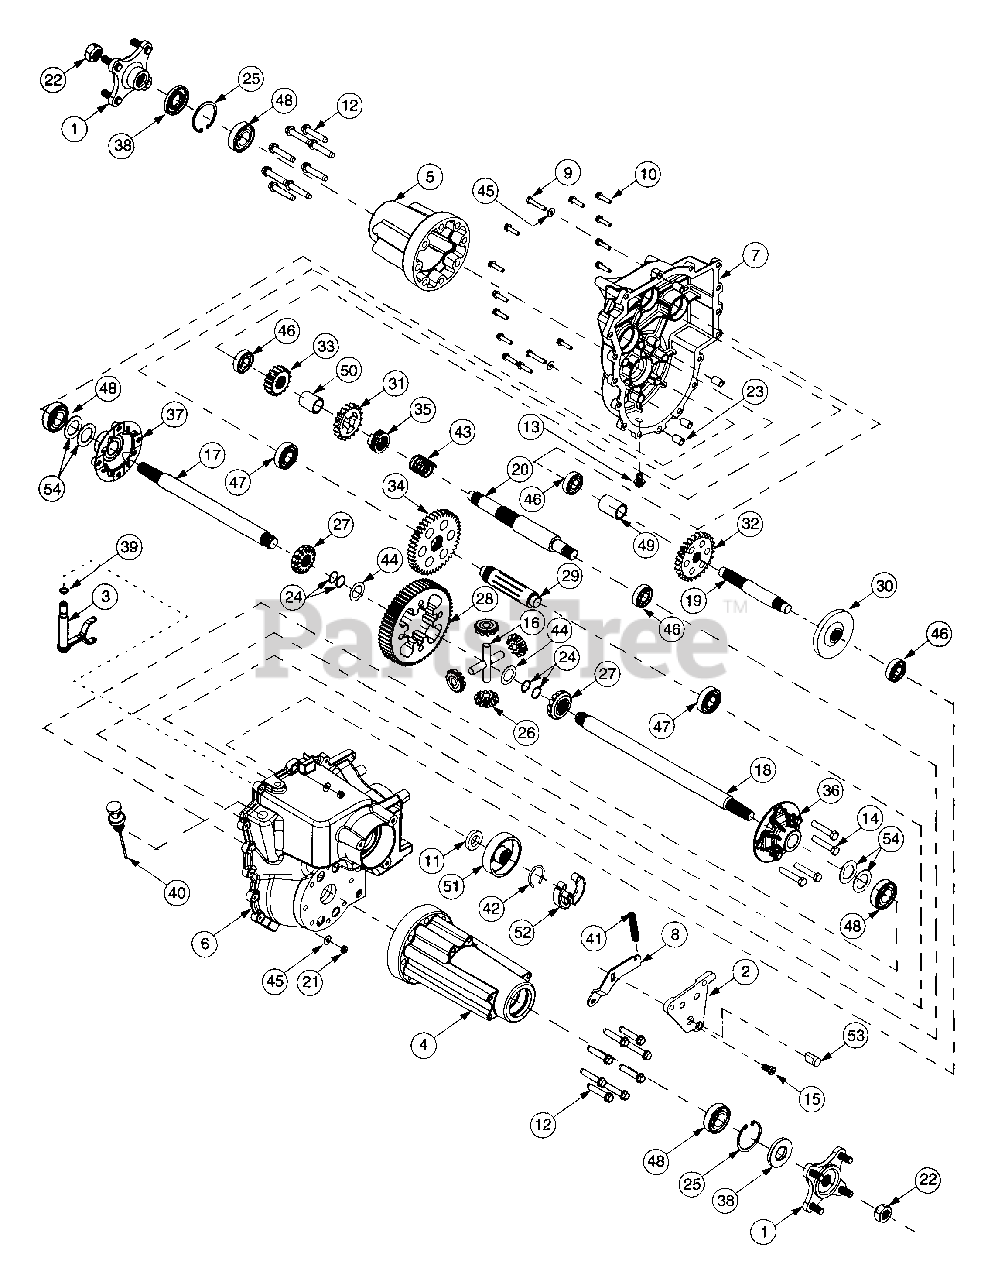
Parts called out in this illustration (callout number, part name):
1	Hub Assembly, Wheel
2	Plate Assembly, Brake
3	Shift Yoke Assembly
4	Axle Housing, RH
5	Axle Housing, LH
6	Transmission Housing, RH
7	Transmission Housing, LH
8	Brake Arm
9	Screw, Hex Cap, 1/4-20 x 1.5
10	Screw, Hex Wash Hd Tap, 1/4-20 x 1.0
11	Seal, Shift Shaft
12	Screw, TT, 3/8-16 x 1.875
13	Screw, Plug, M14 x 1.5 x .827
14	Screw, Hex Hd Cap, 3/8-24 x 2.0 GR5
15	Screw, Cap, 3/8-16 x .750
16	Shaft, Cross, .500 x 3.005
17	Shaft, Axle, 1.00 x 12.90
18	Shaft, Axle, 1.00 x 16.62
19	Shaft, Drive
20	Shaft, Shifter
21	Nut, Hex Center Lock, 1/4-20
22	Nut, Hex, 3/4-16
23	Dowel Bushing
24	Ring, Retaining, .750
25	Ring, Retaining,
26	Gear, Miter, 10T
27	Gear, Miter, 14T
28	Gear, Differential Spur, 60T
29	Shaft Out ut 9T
30	Gear, Bevel, 36T
31	Gear, Spur, 18T
32	Gear, Spur, 27T
33	Gear, Spur, 16T
34	Gear, Spur, 42T
35	Collar, Drive
36	Housing, Differential, RH
37	Housing, Differential, LH
38	Seal, Oil, 25.4mm x 54mm x 7mm
39	O-Ring, 3/8 1 D x 1/2 OD x 1/16 Thk
40	Dipsick, Oil
41	Spring, Compression
42	Spring, Brake
43	Spring, Compression, 1.015 ID x 1.6
44	Washer, Flat, 1.0 x 1.56 x .010 Thk
45	Washer, Flat, .25 x .630 x .0515
46	Bearing, Ball, 17 ID x 40 OD x 12
47	Bearing, Ball, 6204
48	Bearing, Ball, 6205-1
49	Spacer, .757 x 1.0 x 1.460
50	Spacer, .885 x 1.125 x 1.40
51	Drum, Brake
52	Brake, Shoe
53	Brake, Actuator
54	Washer, Flat, 1.010 x .56 x .060
